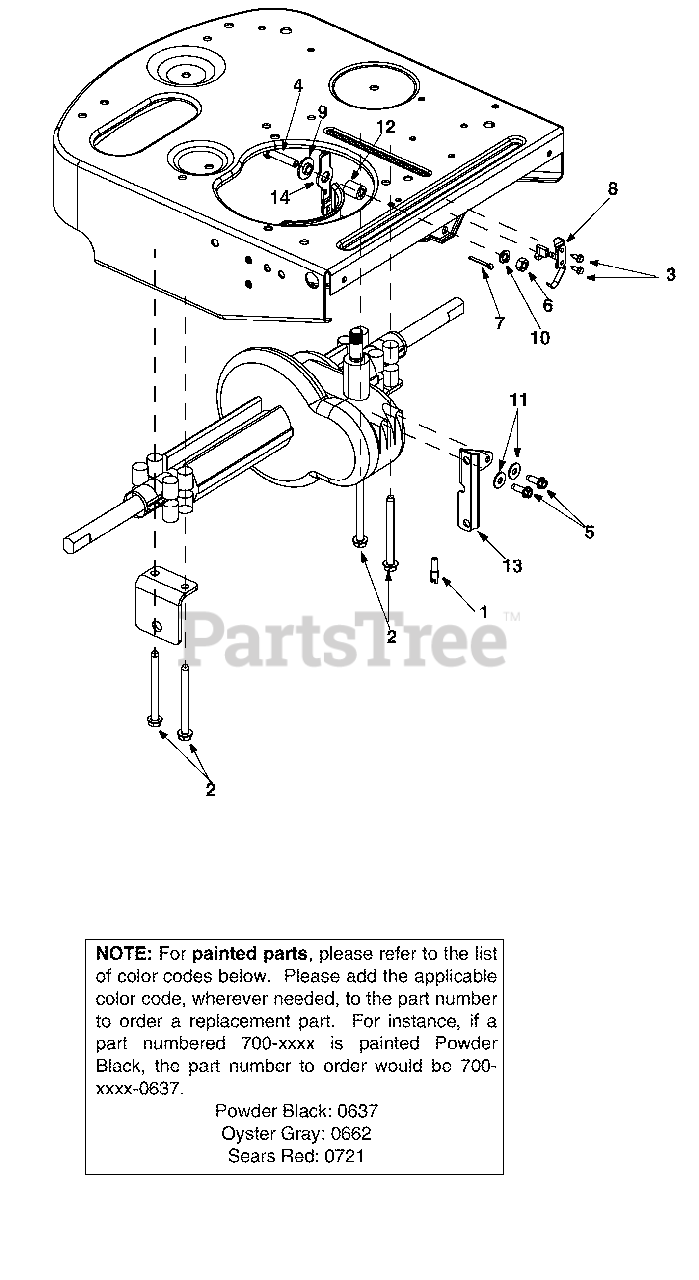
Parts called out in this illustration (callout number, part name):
1	Harness Assembly Adapter
2	Hex TT Screw 5/16-18 x 3.50
3	Hex Washer Head Self-Tap.Scew
4	Hex Screw 5/16-18 x 1.5 Gr. 5
5	Thd. Forming Scr. 1/4-20x .75
6	Hex Nut 5/16-18
7	Cotter Pin
8	Insulator Nut Plate
9	Shoulder Bushing
10	Lock Washer 5/16
11	Flat Washer
12	Spacer
